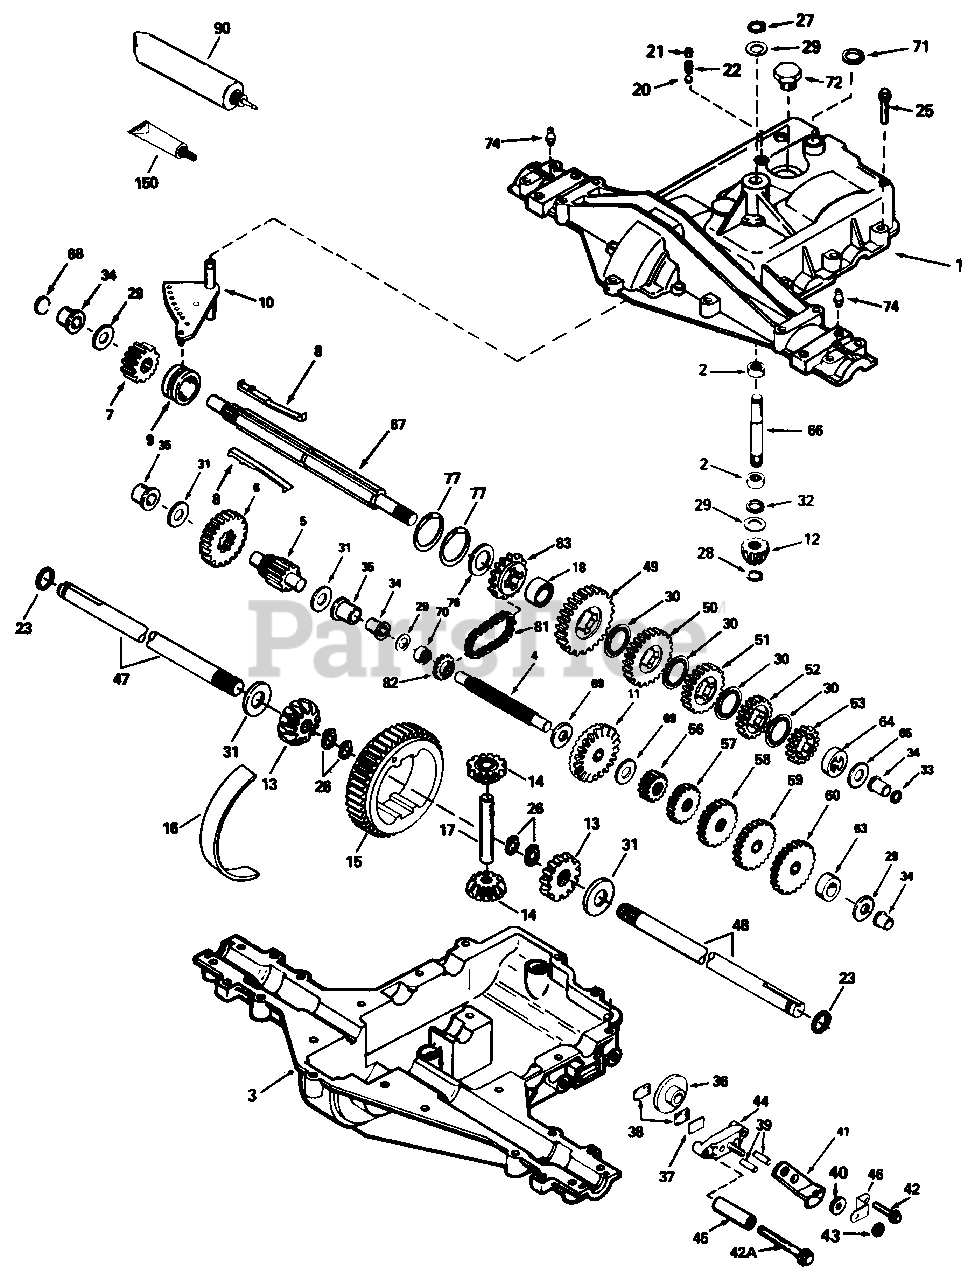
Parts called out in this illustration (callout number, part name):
1	COVER, Transaxle
2	BEARING, Needle
3	CASE, Transaxle
4	SHAFT, Counter
5	SHAFT & PINION ASSY., Output
6	GEAR, Output
7	GEAR, Spur (15 teeth)
8	KEY, Shifter
9	COLLAR, Shifter
10	ROD & FORK ASSY., Shift
11	GEAR, Bevel (42 teeth)
12	BEVELPINION, Input
13	GEAR, Bevel
14	GEAR, Bevel Pinion
15	GEAR, Ring
16	STRIP, Bearing
17	PIN, Drive
20	BALL, Steel (5/16" dia.)
21	SCREW, Set, 3/8-16 x 3/8
23	RING, Seal
25	SCREW, Flanged Hex Hd., Threadforming, 1/4-20 x 1-1/4
26	RING, Retainer (Pkg. of 2)
27	RING, Retainer
28	RING, Retainer
29	WASHER, Thrust
30	WASHER, Thrust
33	SEAL, Square Cut
34	BUSHING, Flanged
35	BUSHING, Flanged
36	DISK, Brake
37	PLATE, Brake Pad
38	PAD, Brake
39	PIN, Dowel
40	WASHER, Flat
41	LEVER, Brake
42	SCREW, Flanged Hex Hd., Threadforming, 1/4-20 x 1-1/4
42A	SCREW, Flanged Hex Hd., Threadforming, 1/4-20 x 1-1/4
43	NUT, Lock, 5/16-24
44	HOLDER, Brake Pad
46	BRACKET, Brake Lever
47	AXLE (11-5/32" Long)
48	AXLE (16-27/32" Long)
49	GEAR, Spur (37 teeth)
50	GEAR, Spur (30 teeth)
51	GEAR, Spur (25 teeth)
52	GEAR, Spur (22 teeth)
53	GEAR, Spur (19 teeth)
56	GEAR, Spur (12 teeth)
57	GEAR, Spur (20 teeth)
58	GEAR, Spur (25 teeth)
59	GEAR, Spur (28 teeth)
60	GEAR, Spur (31 teeth)
65	WASHER, Thrust
66	SHAFT, Input
67	SHAFT, Brake (4-Keyed)
69	WASHER, Thrust
71	SEAL, Square Cut
72	PLUG, Hex Hd., 9/16-18 Thread
74	FITTING, Lubrication
76	WASHER, Thrust
77	RING, Retaining (Pkg. of 2)
81	CHAIN, Roller (No. 41 chain, 22 Links)
82	SPROCKET (10 teeth)
83	SPROCKET (14 teeth)
90	GREASE (32 oz. Bottle Bentonite grease)
150	ADHESIVE (Loctite #515)
